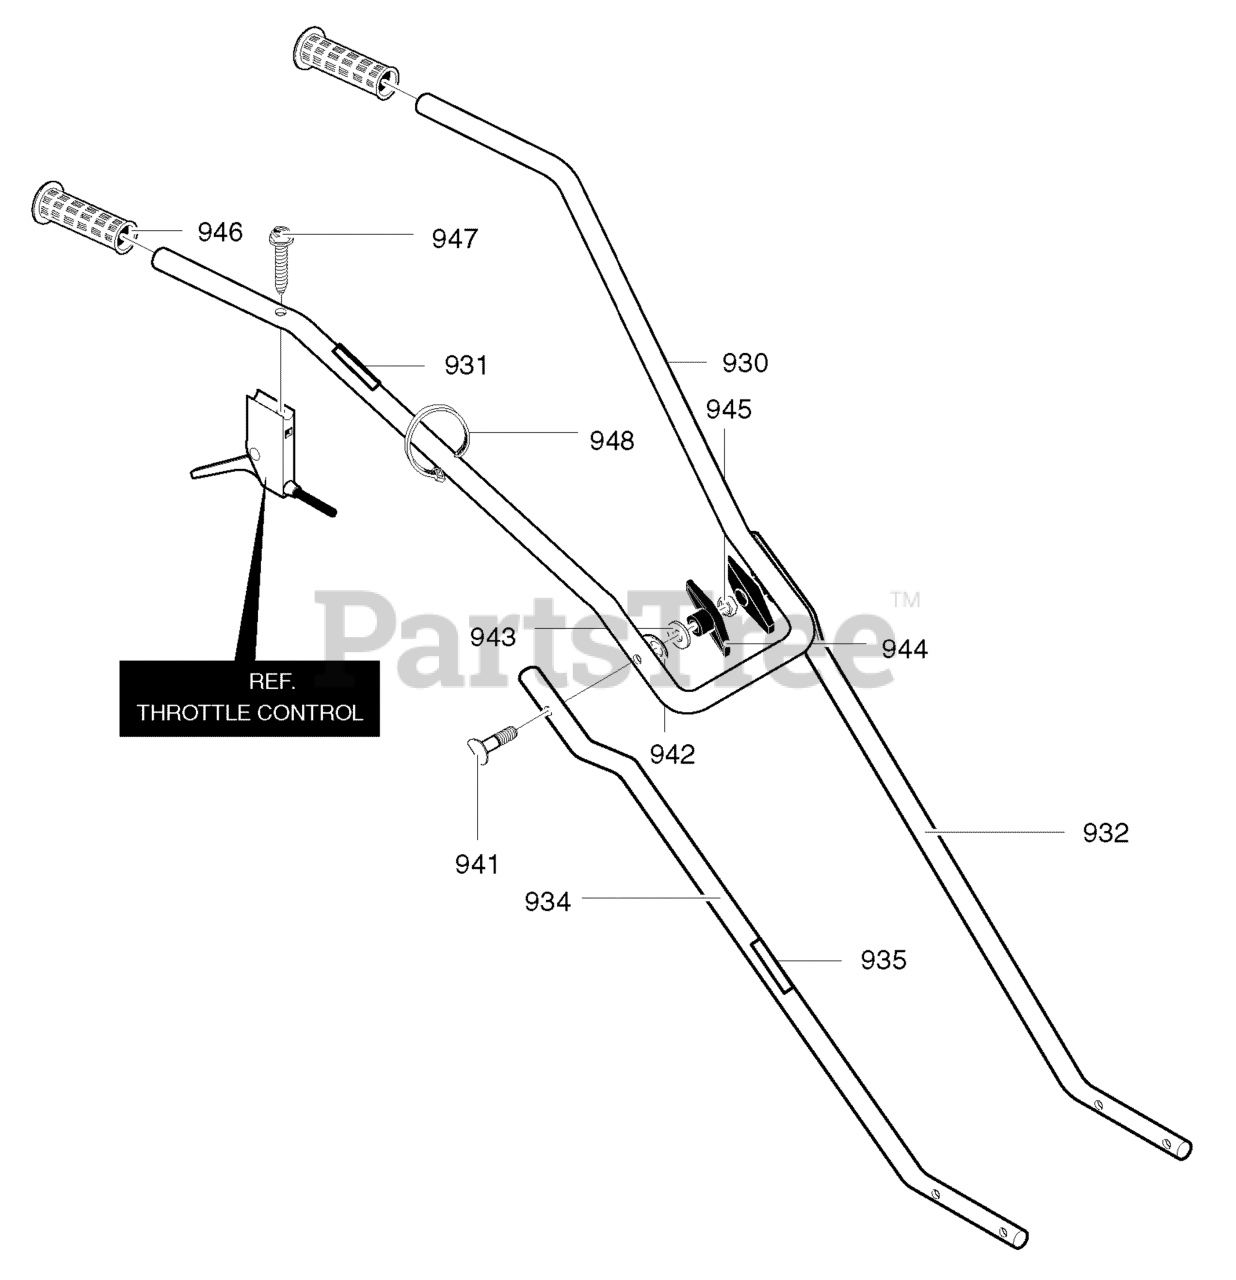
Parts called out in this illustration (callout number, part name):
930	Upper Handle
931	Decal, Throttle Control
932	Lower Handle LH
934	Lower Handle RH
935	Decal, Starting
941	Bolt 5/16-18x1.63
942	Formed Washer
943	Flat Washer
945	Nut, 5/16-18
946	Hand Grip
948	Cable Tie
